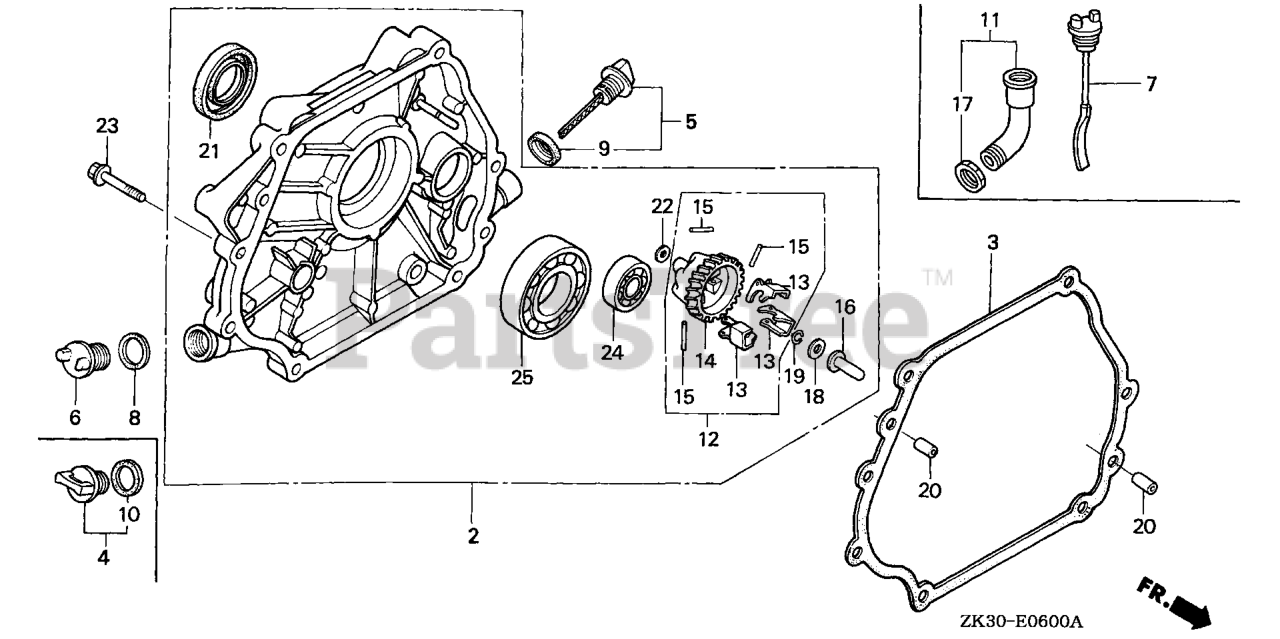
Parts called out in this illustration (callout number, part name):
2	COVER ASSY., CRANKCASE (Q-TYPE)
2	COVER ASSY., CRANKCASE
3	GASKET, CASE COVER
4	CAP ASSY., OIL FILLER
5	CAP ASSY., OIL FILLER
9	GASKET, OIL FILLER CAP
10	GASKET, OIL FILLER CAP
12	GOVERNOR ASSY.
13	WEIGHT, GOVERNOR
14	HOLDER, GOVERNOR WEIGHT
15	PIN, GOVERNOR WEIGHT
16	SLIDER, GOVERNOR
19	CLIP, GOVERNOR HOLDER
20	PIN, DOWEL (8X12)
21	OIL SEAL (35X52X8)
22	WASHER, PLAIN (6MM)
23	BOLT, FLANGE (8X40) Use up to Engine SN 1003236.
24	BEARING, RADIAL BALL (6202)
25	BEARING, RADIAL BALL (6207)
